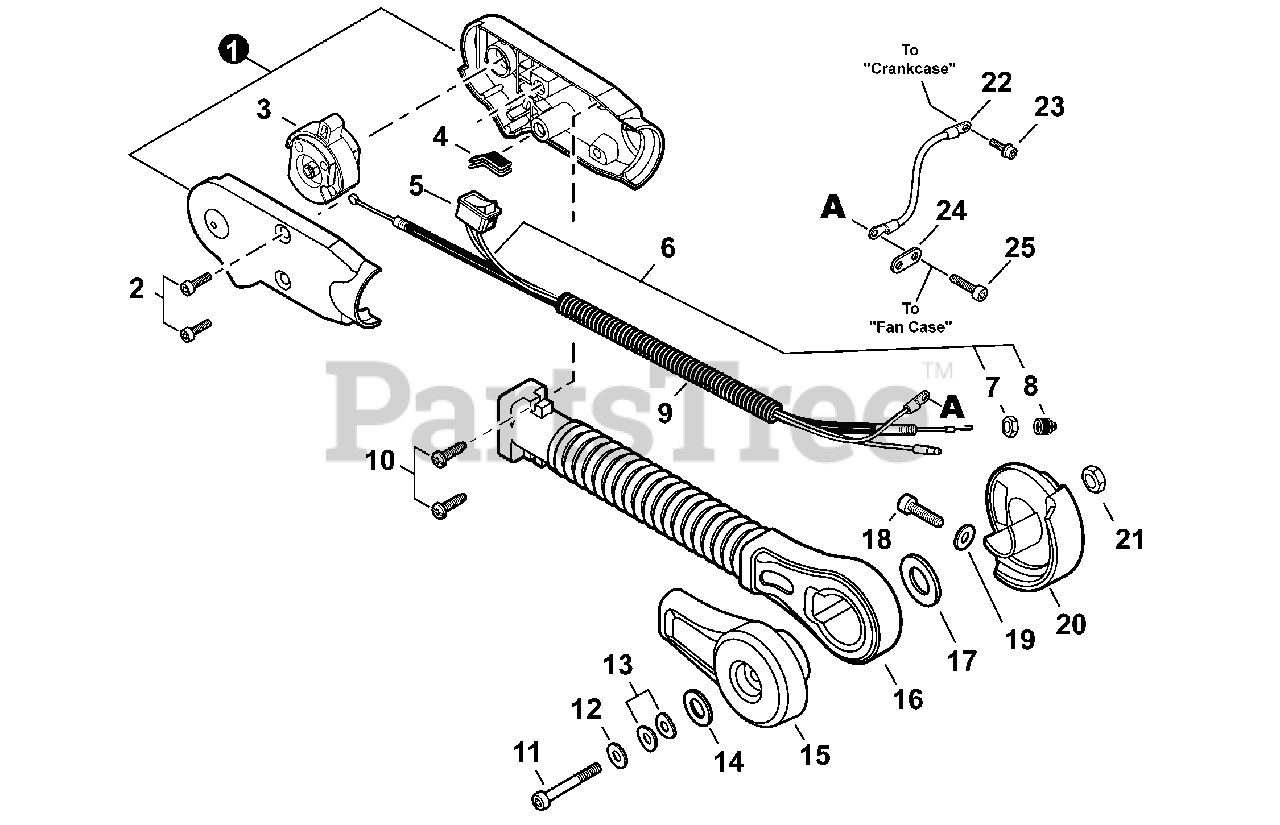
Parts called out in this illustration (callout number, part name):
1	CONTROL HANDLE SET
2	BOLT 5×14
3	CONTROL, THROTTLE
4	GROMMET
5	SWITCH, ON-OFF
6	CABLE, THROTTLE
7	NUT, HEX M6
8	CAP, DUST
9	TUBE, FLEXIBLE
12	WASHER 6.5×15.5×0.6
13	WASHER, FRICTION 6.6×14.3
14	WASHER 6.6×20×1.6
15	BRACKET, ARM - OUTER
16	ARM, THROTTLE CONTROL
17	WASHER 36.5×56×1.0
18	BOLT, TAPPING 5×25
19	WASHER 5.5×16×2T
20	BRACKET, ARM - INNER
21	NUT, LOCK M6
22	LEAD - GROUND
23	BOLT 5×8
24	PLATE, EYE
25	SCREW TAPPING 5×16
